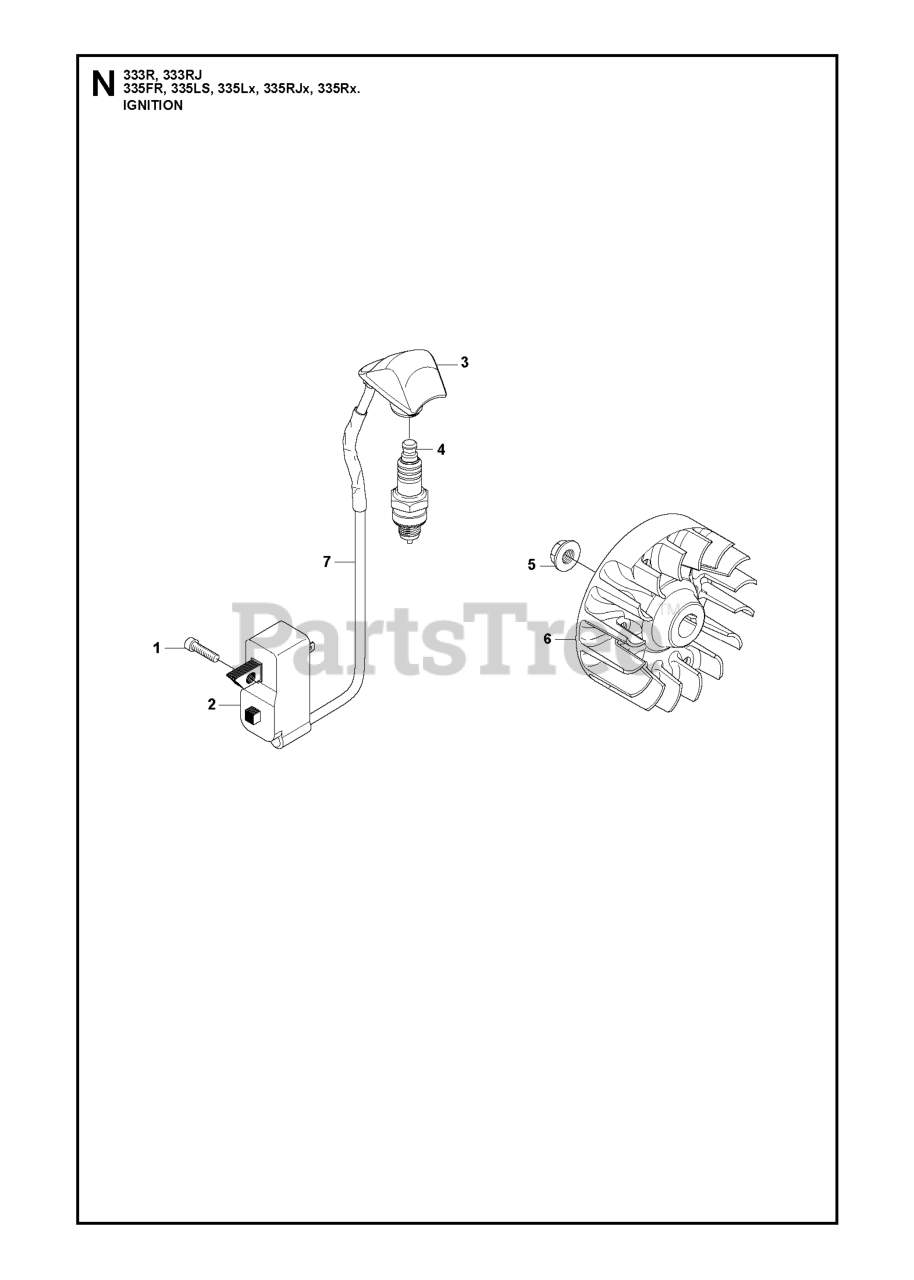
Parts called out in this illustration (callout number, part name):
2	IGNITION MODULE OPS
3	SPARK PLUG CAP
4	SPARK PLUG RCJ6Y NLA
5	FLANGE NUT
6	FLYWHEEL
7	CABLE 13 3/8"IN
